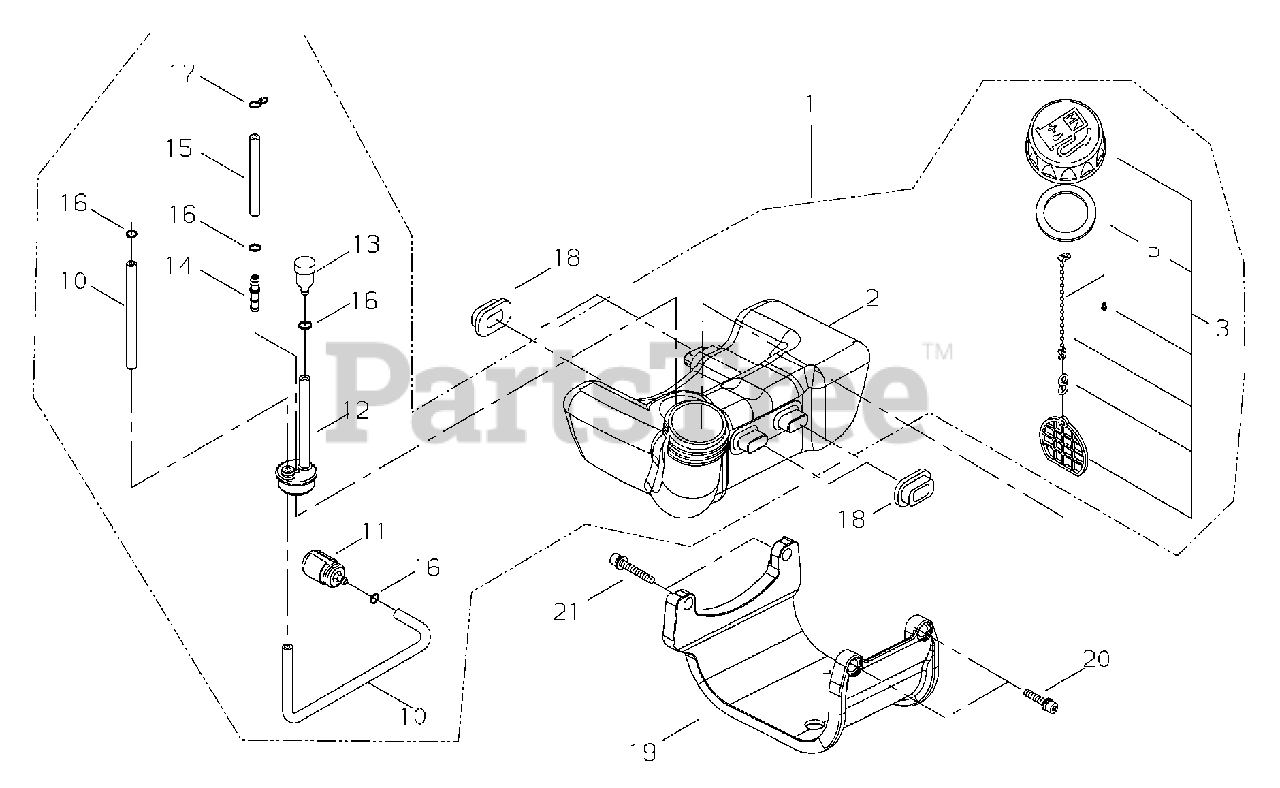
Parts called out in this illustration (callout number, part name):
1	FUEL TANK ASSY
2	TANK, FUEL
3	CAP ASSY
5	GASKET, CAP
10	PIPE - FUEL
11	FILTER, FUEL
12	PIPE ASSY
13	VENT, FUEL TANK
14	CONNECTOR, PIPE
15	PIPE - RETURN
16	RING, RETAINING - 6
17	CLIP - SPRING
18	CUSHION, FUEL TANK
19	GUARD, FUEL TANK
20	SCREW - 5X20
21	SCREW - 5X40
